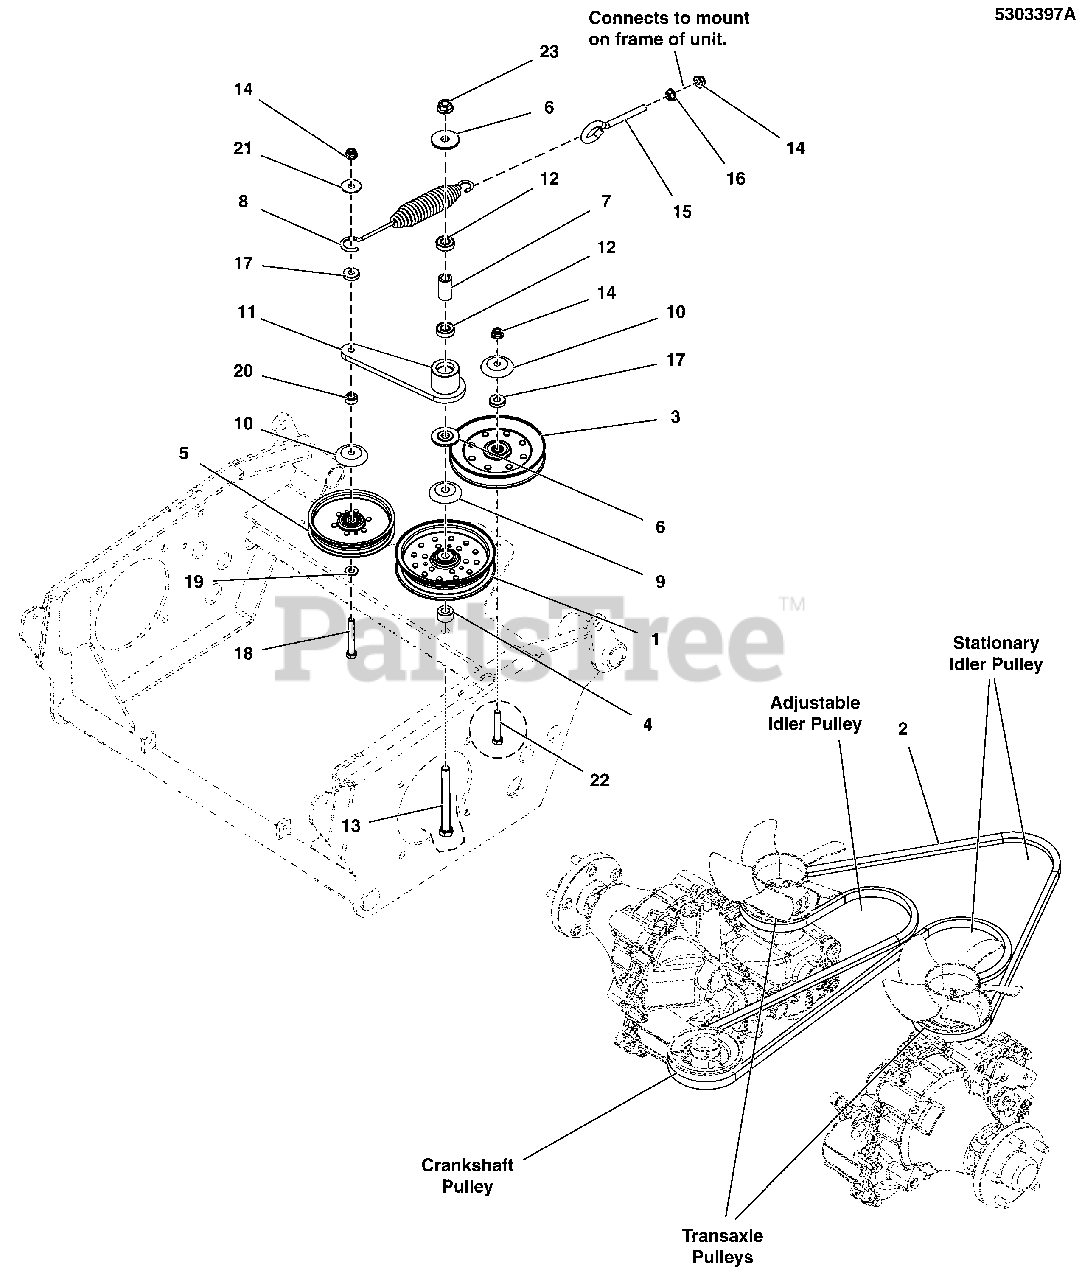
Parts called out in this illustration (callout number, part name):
1	PULLEY, IDLER, 5" OD, 1"FACE, 5.75 FL
2	BELT, B-SEC, 123"EL, TRANSAXLE DRIVE, ARAMID, WRPD
3	PULLEY-IDLER-V, 5.83OB, .38ID, .94W, STL
4	SPACER, .52 X 1.00 X .56, CZ
5	PULLEY, C-SEC, V-IDLER, 6.25"ODX3/8ID
6	SPACER, IDLER ARM, 1/2, PM
7	SPACER, .52 X .84 X 1.53, PM
8	SPRING-EXT, 1.25OD X 9.3LG X .142WR, BLK
9	SHIELD, PULLEY BEARING, CZ
10	SHIELD, BEARING PULLEY, 3/8ID, CZ
11	WELD, IDLER ARM, PUMP DRIVE, 6.38 - BLK
12	BEARING, BALL, AXLE
13	BOLT-1/2-13 X 5 GD5 YZ
14	NUT, 3/8-16 HEX NYLOCK FLANGE
15	EYE BOLT, 3/8-16 X 5, 2.88THRD, 1EYE, CZ
16	NUT, 3/8-16 HEX SERRATED FLANGE
17	SPACER, .39 X 1.00 X .25
18	BOLT, 3/8-16 X 2-3/4" GD5 CZ
19	WASHER, 3/8 GD.9 FLAT
20	SPACER, .39 X 1.00 X .50, CZ
21	WASHER-3/8 FENDER
22	BOLT, 3/8-16 X 2-1/4" GD5 CZ
23	NUT, Hex Flange, Nylock, 1/2-13
